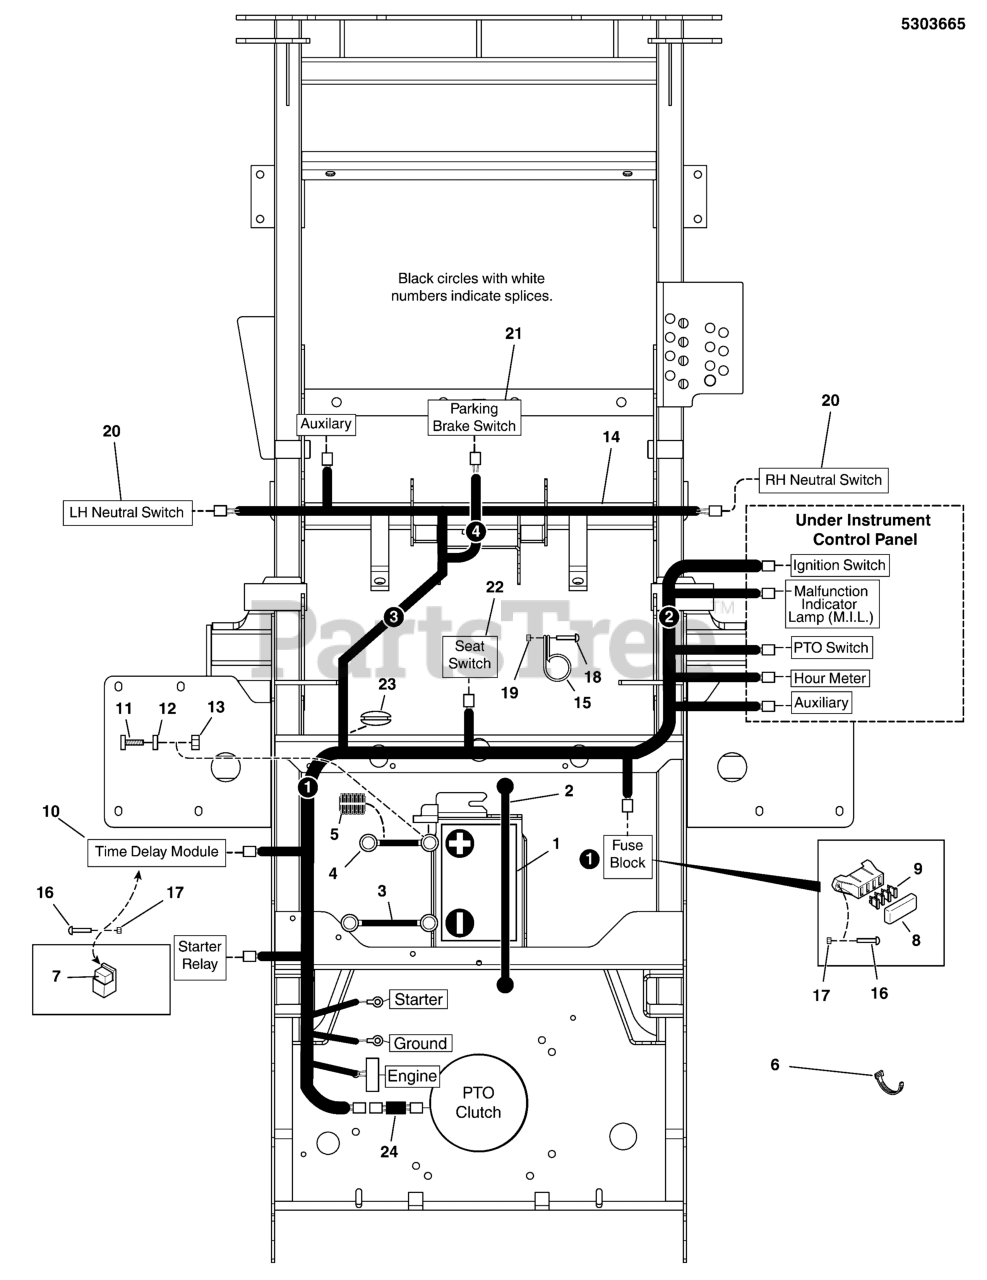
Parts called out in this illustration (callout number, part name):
1	BATTERY, WET ( BCIU1, 350 CCA)
2	STRAP, BATTERY, 14 LONG, Rubber
3	BATTERY CABLE, NEG, 22, 1/4-5/16
4	BATTERY CABLE, POS, 22, 1/4-5/16
5	WIRE LOOM, 3/8 ID X 16 IN
6	TIE, SELF-LOCKING, 12"
7	RELAY, 12 VOLT, 40 AMP
8	COVER, VINYL, FUSE BLOCK
9	FUSE, ATO-20 (20 AMP)(SV)
9	FUSE, ATO-15 (15 AMP)(SV)
10	MODULE, TIME DELAY
11	BOLT, 1/4"-20 X 3/4" GD5 YZ
12	WASHER, 1/4 SAE
13	NUT, 1/4-20 HEX SERR. FLANGE
14	WIRE HARNESS, MAIN, KOHLER 29, IS2100Z
14	WIRE HARNESS, 810 OPTIMUM EFI, IS2100Z
15	CLAMP, VINYL INSULATED, 1.00
16	SCREW, #10-24 X 3/4" ROUND PHILLIPS
17	NUT, Hex, Nylon Lock, #10-24
18	SCREW, 1/4-20 X 1, ALLEN BH, CZ
19	NUT,1/4-20,GR5,HEX,ZC/CL
20	SWITCH, PLUNGER, NO, SINGLE POLE, SNAP-IN
21	SWITCH, PLUNGER, NO/NC SNAP-IN, LOW PROFILE
22	SWITCH, PLUNGER, N.C.
23	GROMMET, 1-1/2" ID FOR 1/4" METAL
24	CLUTCH JUMPER W/ DIODE, WARNER
